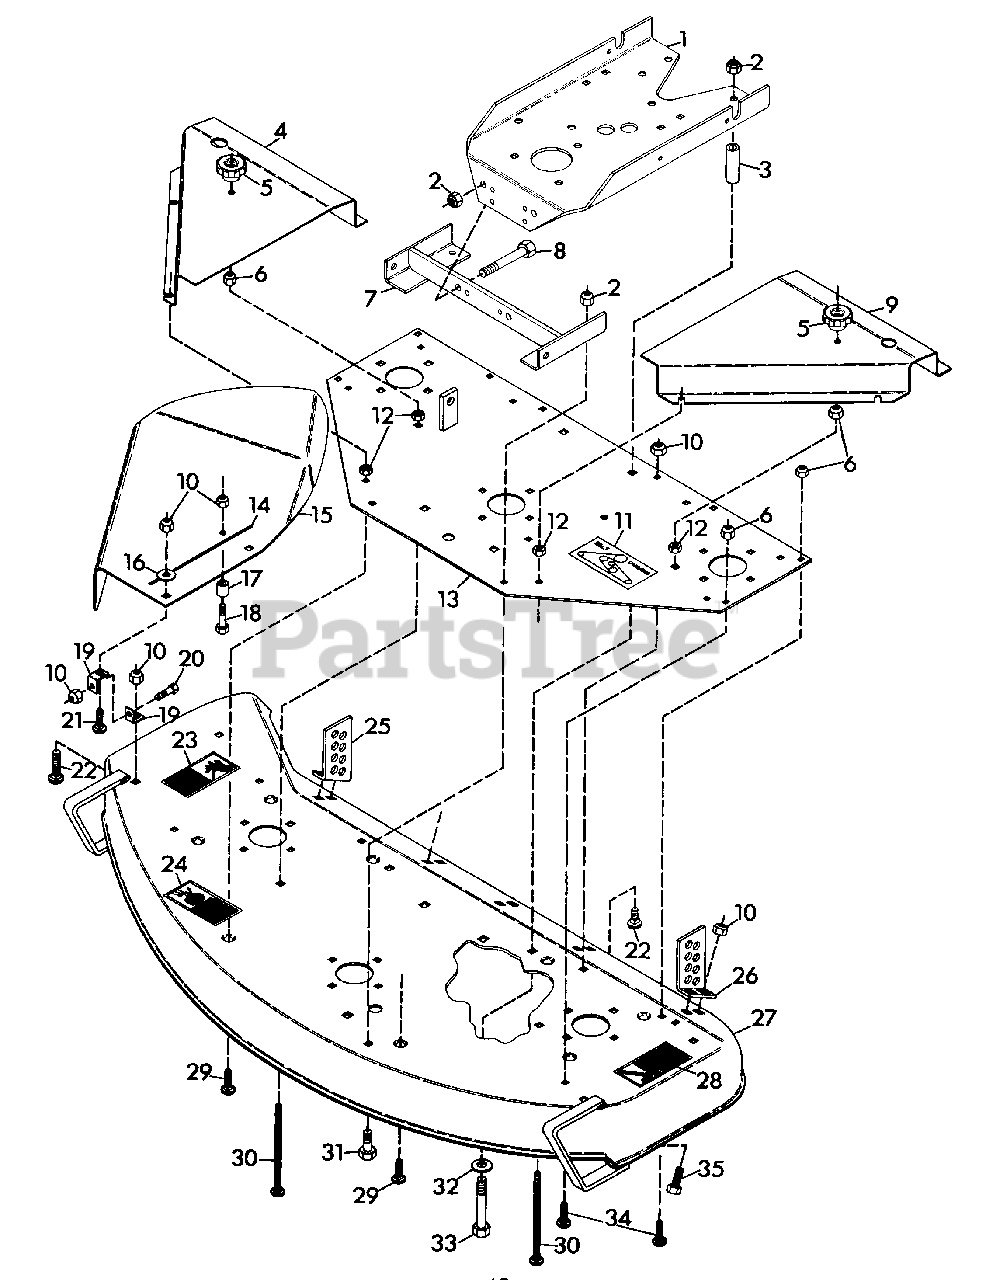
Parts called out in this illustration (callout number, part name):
1	SUPPORT, GEAR HOUSING
2	NUT, LOCK 1/2-13
3	SPACER, .510X.840X2.43
4	COVER, PULLEY R.H.
5	KNOB
6	NUT, LOCK 5/16-18
7	BRACKET, HEIGHT ADJUSTMENT
8	BOLT, HEX 1/2-13X1.375
9	COVER, PULLEY L.H.
10	NUT, LOCK 3/8-16
11	DECAL, BELT INSTALLATION
12	NUT, JAM 5/16-18
13	WELDMENT, SUPPORT PLATE
14	STRIPE
15	SHIELD, SAFETY EXTENSION 50" MOWER
16	WASHER, FLAT .406X.812X.065
17	STOP, CHUTE
18	BOLT, HEX 3/8-16X1.50
19	TAB, SPRING
20	BOLT, HEX 3/8-16X.875
21	BOLT, 3/8-16X1.00 RD HD SQ NK
22	BOLT, CARRIAGE 3/8-16X.75
23	DECAL, DANGER HAND
24	DECAL, WARNING EYE
25	PLATE, REAR ADJUSTMENT
26	PLATE, REAR ADJUSTMENT
27	WELDMENT, 50 INCH DECK
28	DECAL, DANGER FOOT
29	BOLT, CARRIAGE 5/16-18X1.00
30	BOLT, HEX 5/16-18X3.50
31	BOLT, HEX 1/2-13X1.25
32	WASHER, FLAT .531X1.062X.095
33	BOLT, HEX 1/2-13X3.75
34	BOLT, CARRIAGE 5/16-18X.75
35	BOLT, HEX 3/8-16X1.25
NS	DECAL, MOWER
NS	DECAL, GRAVELY LOGO
